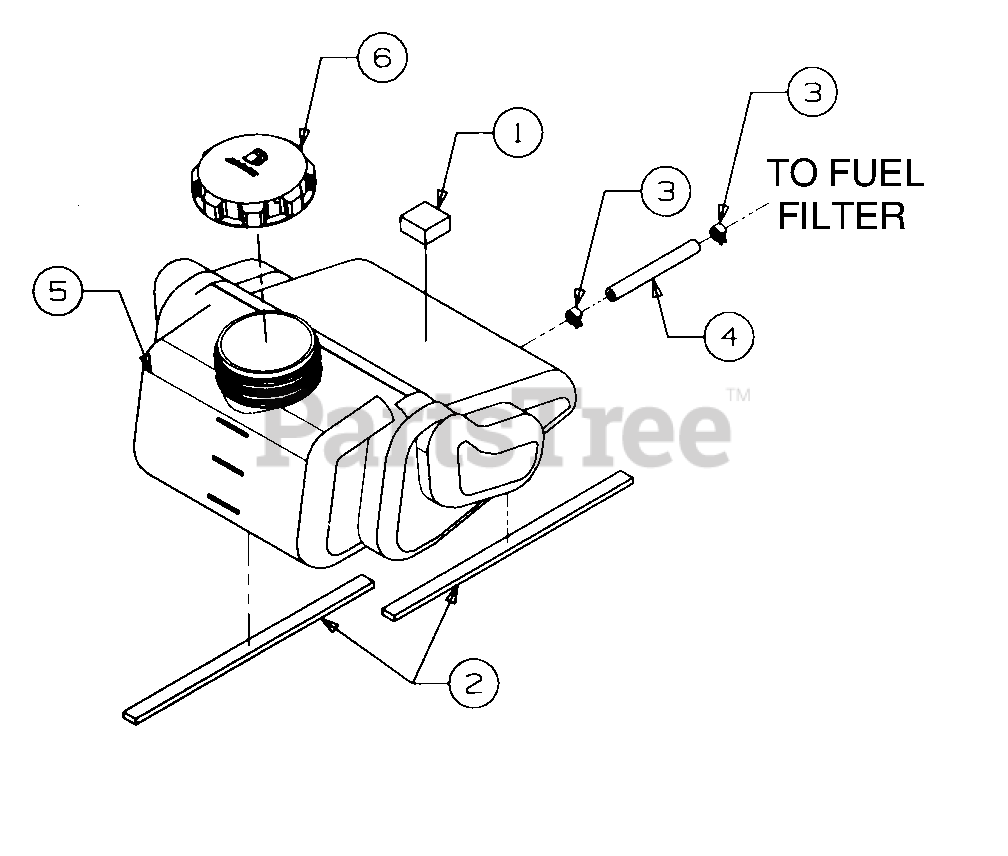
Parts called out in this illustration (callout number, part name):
1	Foam, 1.25 Sq x .62 Thk
2	Tape, Foam, .625 Wide x .25 Thk
3	Clamp, Hose
4	Line, Fuel, 72" (Shipped In 10ft Length)
5	Tank, Fuel
6	Cap, Fuel
